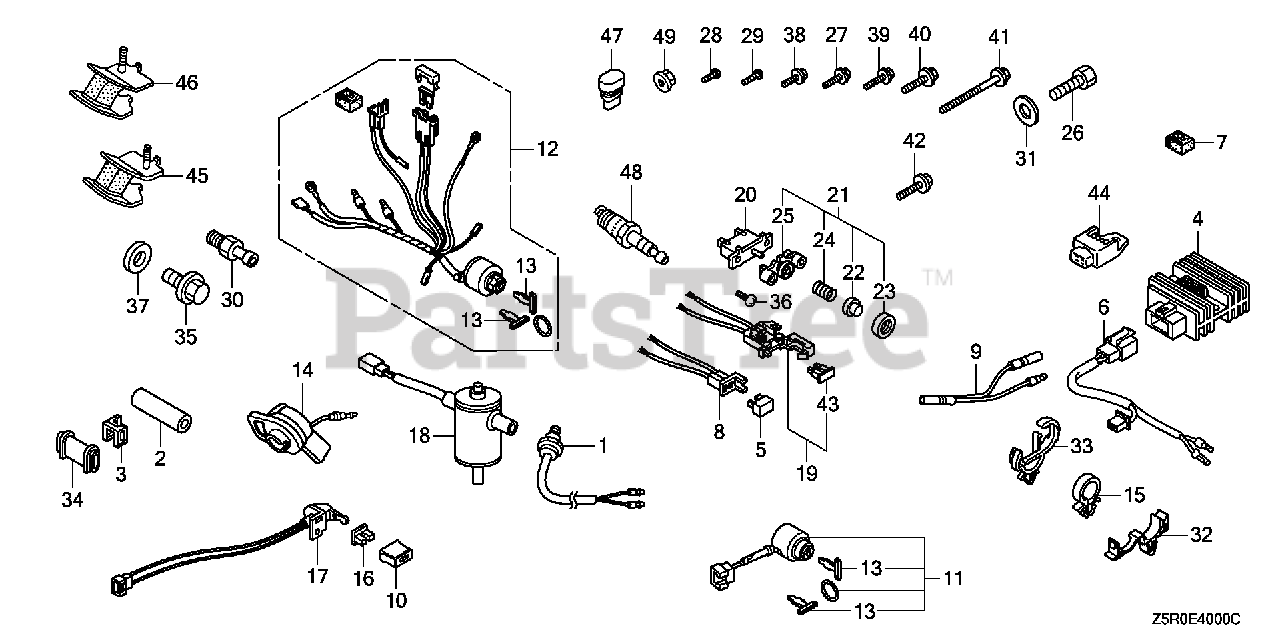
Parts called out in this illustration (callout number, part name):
4	RECTIFIER ASSY., REGULATOR (10A)
6	SUB-WIRE HARNESS ASSY.
30	PLUG, OIL DRAIN
35	BOLT, DRAIN PLUG (12MM)
37	WASHER, DRAIN PLUG (12MM)
